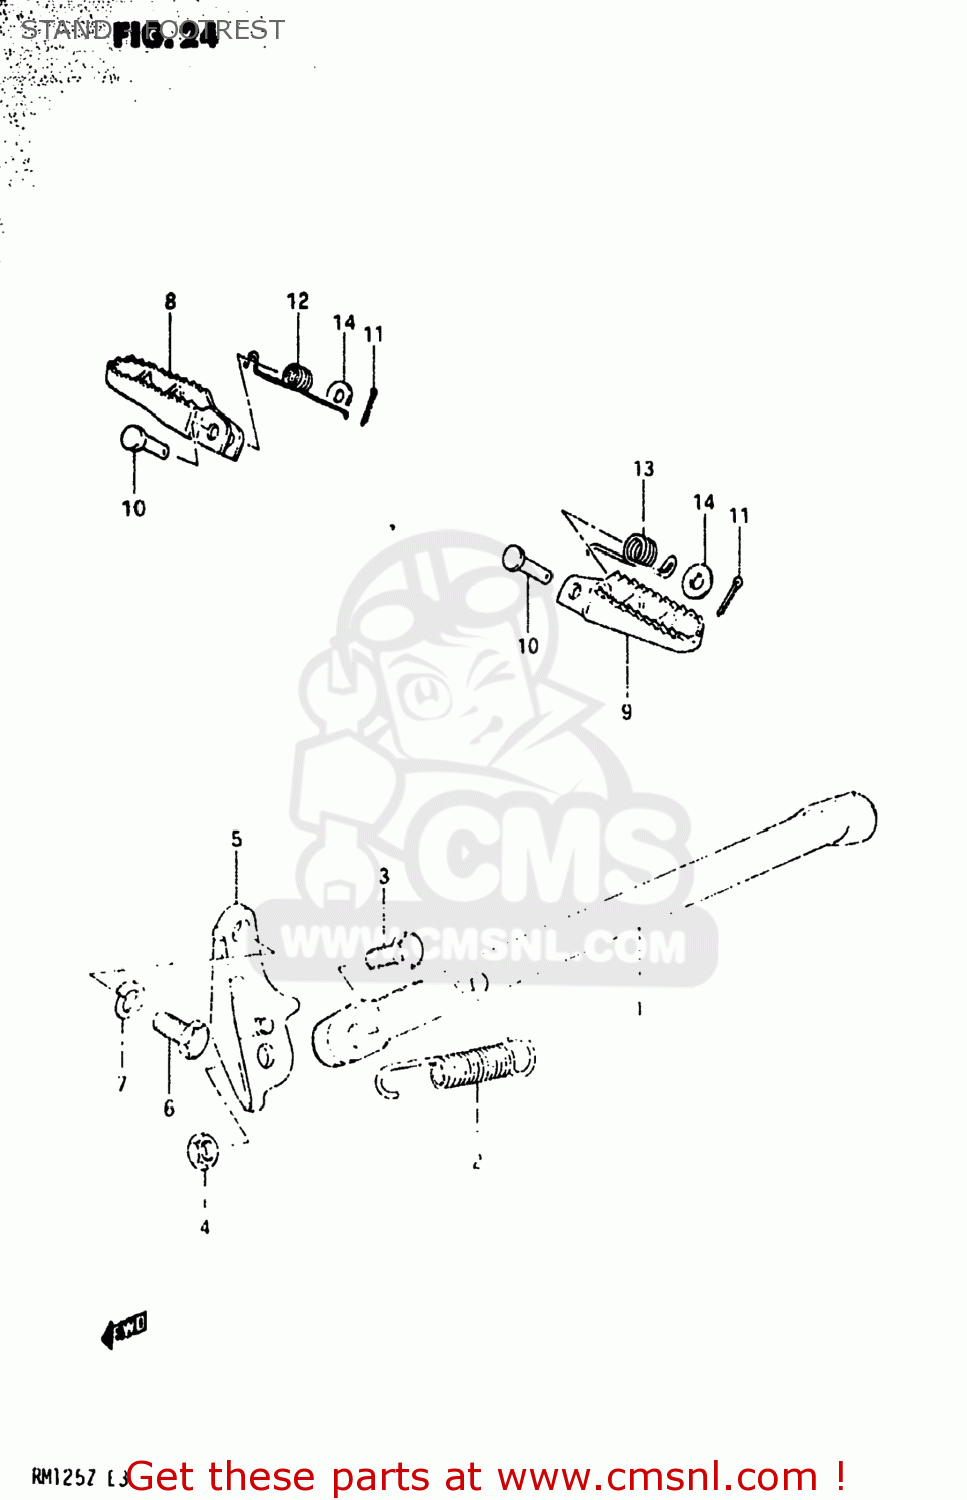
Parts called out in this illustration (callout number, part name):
1	STAND,SIDE
2	SPRING
3	BOLT(10X30)
4	NUT
5	BRACKET,SIDE STAND
6	BOLT(10X19)
7	LOCK WASHER
8	RUBBER,FRONT FOOTREST
9	FOOTREST
10	PIN
11	PIN 20X20
12	SPRING
13	SPRING
14	WASHER
